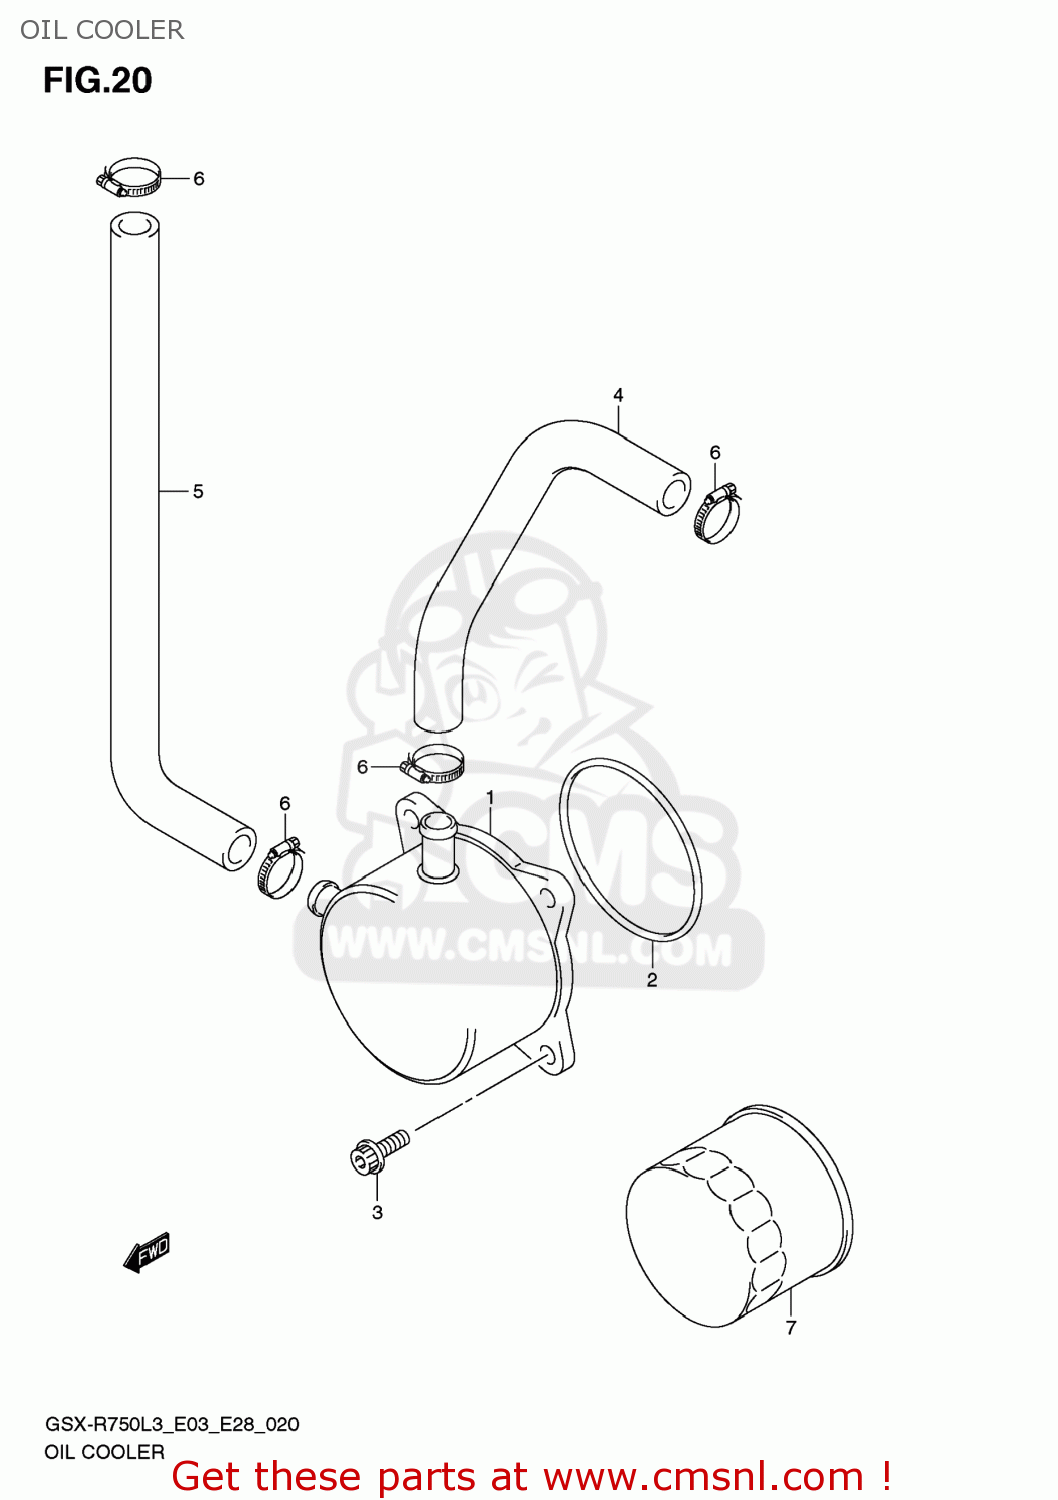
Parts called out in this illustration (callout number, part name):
1	COOLER ASSY,OIL
2	O RING(D:3.1,ID:63.9)
3	BOLT(6X16)
4	HOSE,OIL COOLER WATER INLET
5	HOSE,OIL COOLER WATER OUTLET
6	CLAMP
7	FILTER ASSY,ENGINE OIL
